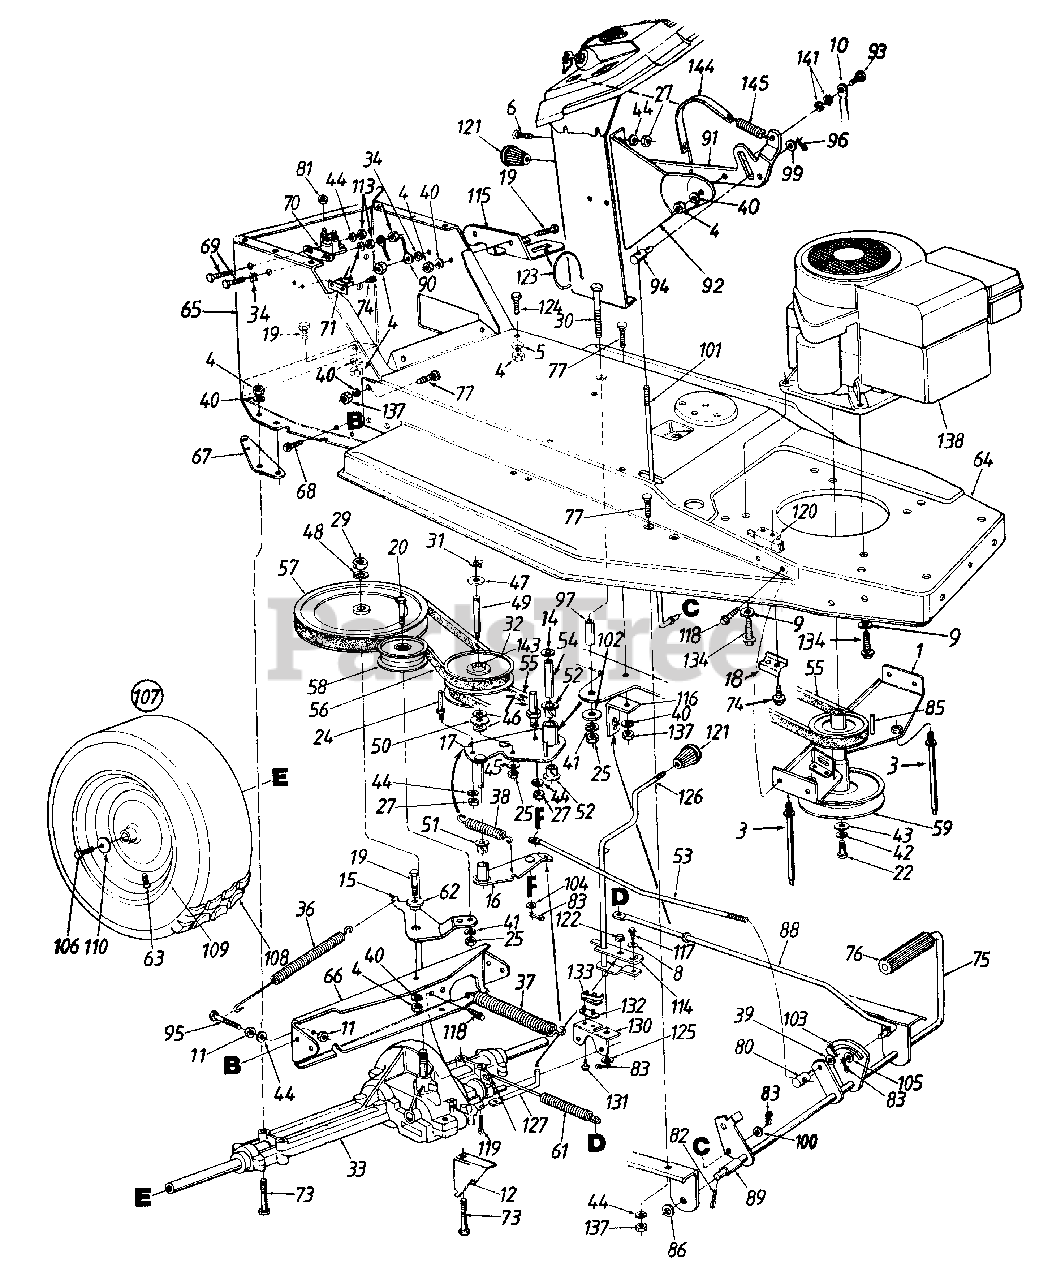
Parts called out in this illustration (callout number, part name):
3	Belt Guard Pin 5/16-18 x 4.75" Lg.
4	Hex Nut 5/16-18 Thd.
5	Bell-Washer .345" I.D. x .88
6	Truss-Mach. Scr. 1/4-20 x .50"
7	Belt Guard Pin 1/4-20 Thd.
8	Bell-Washer .265" I.D. x .75
9	Flat Washer 3/8" I.D. x .97" O.D.
14	Flat Washer 3/8" I.D. x 1.26" O.D.
19	Hex Bolt 5/16-18 x .75" Lg.
20	Hex Bolt 3/8-24 x 2.0" Lg. Gr. 5
22	Hex Bolt 7/16-20 x 1.5" Lg.
24	Belt Guard Pin
25	Hex Nut 3/8-24 Thd.
27	Hex Nut 1/4-20 Thd.
29	Hex Jam Nut 9/16-18 Thd.
30	Hex Bolt 3/8-24 x 3.75" Lg.
31	Snap Ring
32	Variable Speed Pulley Ass'y.
33	Transaxle Ass'y. Comp.
34	Ext. Lock Washer 5/16" I.D.
36	Extension Spring 6.12" Lg.
37	Extension Spring 6.74" Lg.
38	Extension Spring 2.59" Lg.
39	Flat Washer .385" I.D. x .620"
40	Lock Washer 5/16" I.D.
41	Lock Washer 3/8" I.D.
42	Lock Washer 7/16" I. D
43	Flat Washer .450" I.D. x 1.25"
44	Lock Washer 1/4" I.D.
45	Bell-Washer .39" I.D. x 1.13"
46	Flat Washer .56" I.D. x 1.0" O.D.
47	Washer Teflon .565 I.D.
48	Bell-Washer 9/16" I.D. x 1.125" O.D.
49	Shaft .56" Dia. x 3.875" Lg.
50	Thrust Brg. 1.25 O.D.
51	Flanged Nyliner Brg.
52	Nyliner Flanged Brg.
53	Speed Control Rod
54	Spacer
55	V-Belt
56	V-Belt
57	V-Pulley 8" Dia.
58	Idler Pulley 3-1/8" Dia.
59	Engine Pulley 6.0" Dia. x 3.56"
61	Extension Spring 7.08" Lg.
62	Shld. Spacer .500" Dia.
63	Air Valve
69	Hex Bolt 1/4_20 x .62" Lg.
70	Solenoid
71	Circuit Breaker
73	Hex Bolt 5/16-18 x 2.75" Lg.
74	Truss Mach. B-Tap Scr. #10 x .50" Lg.
77	Ribbed Neck Bolt 5/16-24 x .84"
80	Ferrule
81	Hex Sems Nut 1/4-20 Thd.
82	Cotter Pin 1/8" Dia. x 1.25" Lg.
83	Cotter Pin 3/32" Dia. x .75" Lg.
85	Sq. Key 1/4 x 2.0" Lg.
86	Flat Washer .635" I.D. x 1.0"
88	Brake Rod
89	Spacer 5/8" I.D. x 1.2" Lg.
90	Ground Wire 7.25" Lg.
91	Speed Selector Lever
92	5 Spd. Selector Brkt.
93	Shld. Bolt .437" Dia. x .47" Lg.
94	Ferrule
95	Hex Bolt 1/4-28 x 1.25" Lg.
96	Internal Cotter Pin 5/16" Dia.
97	Spacer .375" I.D. x .625"
99	Flat Washer .344" I.D. x .62"
100	Flat Washer .25" I.D. x .62" O.D.
101	Speed Control Rod
102	FlatWasher3/8" I.D. x 1.25" O.D.
103	Cotter Pin 1/8" Dia. x 1.0" Lg.
104	Flat Washer .34" I.D. x .68"
105	Flat Washer.34" I.D.
106	Hex Lock Bolt 5/16-24 x .75" Lg.
110	Bell-Washer .345" I.D. x .88"
113	HexJam Nut 1/4-20 Thd.
114	Shift Lever Adjusting Link
115	Shift Lever Spring Brkt.
118	Hex Washer Hd. Tap Scr. 1/4-20 x .5" Lg.
119	Internal Cotter Pin
120	Safety Switch (Clutch)
121	Knob
122	Retaining Ring
123	Compression Spring 1.5" Lg.
124	Hex Washer Hd. Scr. 5/16-18 x 7/8" Lg.
125	Flat Washer .469" I.D. x .88"
130	Shift Lever Support
131	Hex Washer Hd. #8 x .50" Lg.
132	Insulator Nut Plate
133	Spring Switch
134	Hex Tap Scr. 3/8-16 x 1.25"
137	Hex Nut 5/16-24Thd.
138	Engine
141	Wave Washer .445" I.D.
143	Needle Brg.
144	7 Spd Indicator Strip
145	Ext. Spring 2.04" Lg.
